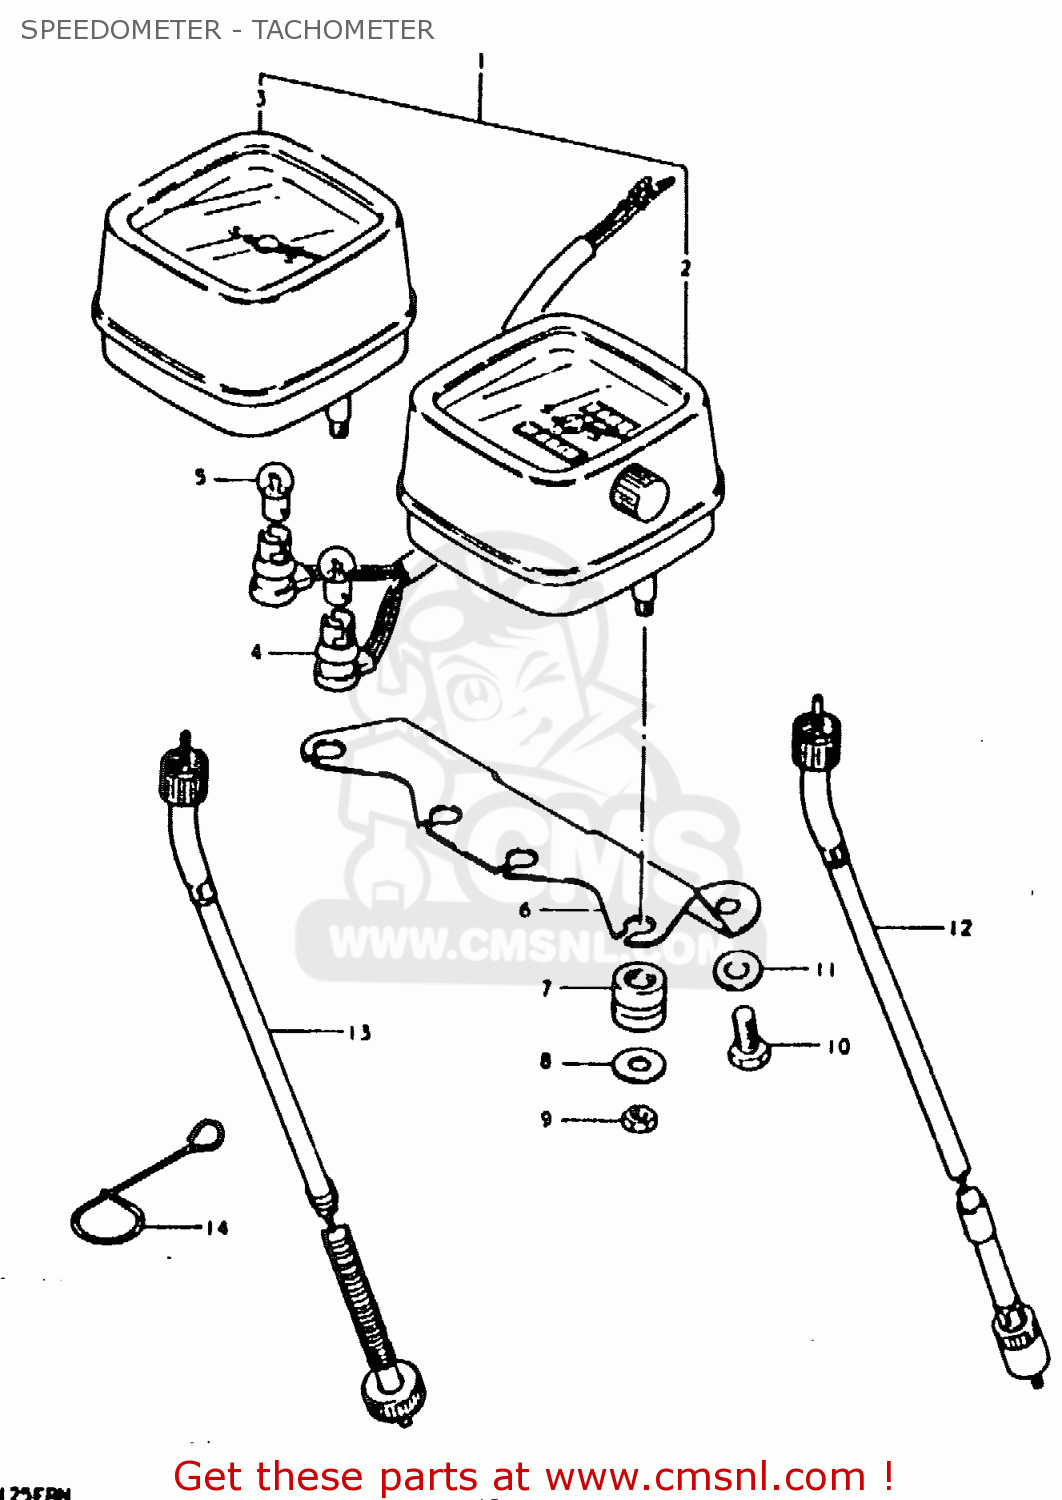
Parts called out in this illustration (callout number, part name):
1	SPEEDOMETER & TACHOMETER ASSY
2	SPEEDOMETER
3	TACHOMETER
4	SOCKET
5	BULB(6V1.7W,STANLEY,A61A)
6	BRACKET
7	CUSHION
8	WASHER,METER
9	NUT
10	BOLT, UPPER
11	WASHER
12	CALBE ASSY, SPEEDOMETER
13	CABLE ASSY, TACHOMETER
14	GUIDE,TACHOMETER CABLE
